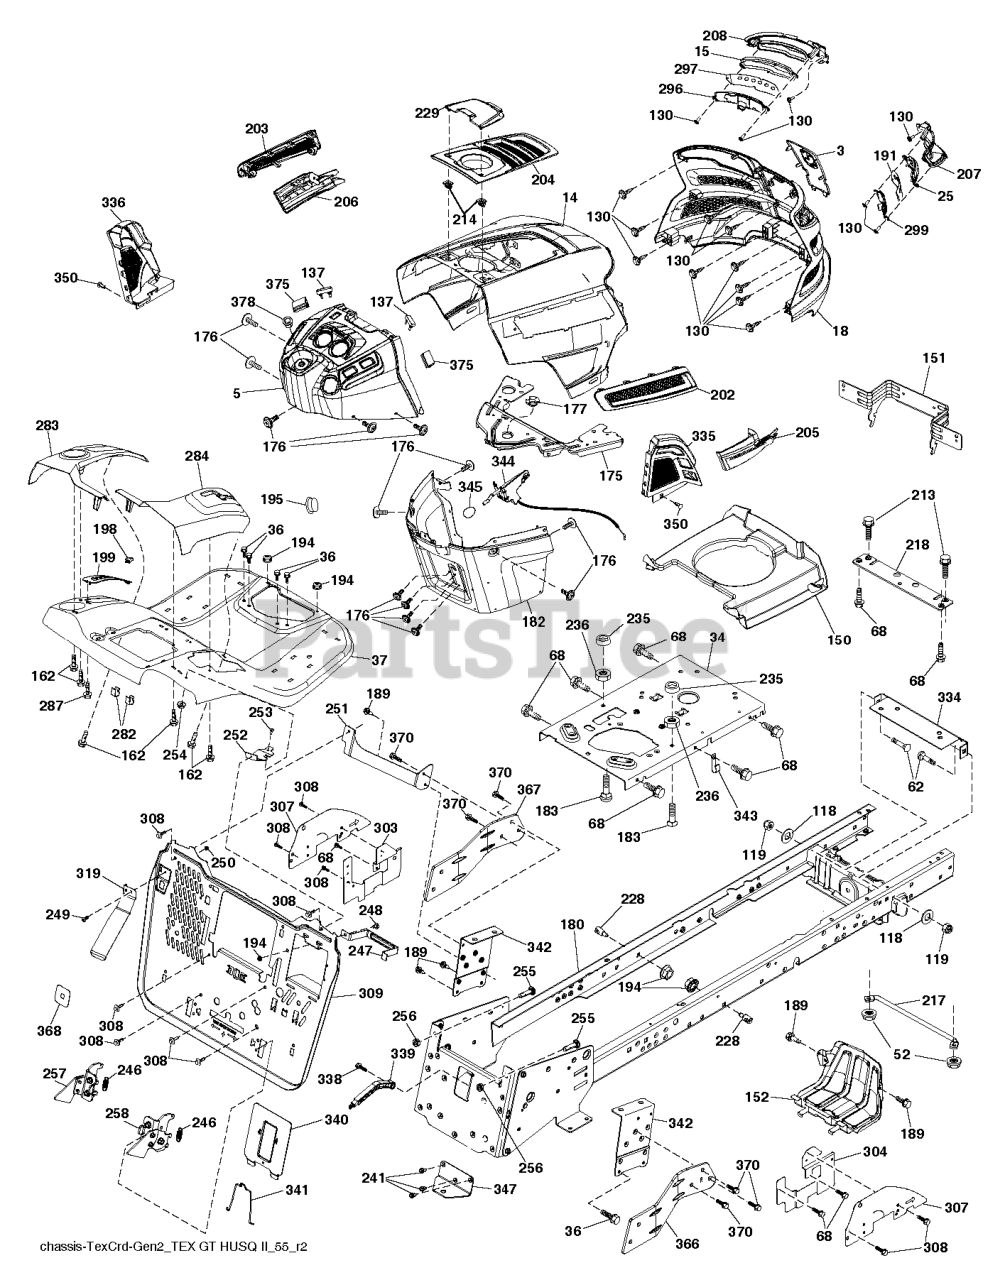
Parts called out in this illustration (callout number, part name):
3	APPLIQUE.SUBASM.GT.HUSQ.II
5	DASH.UPR.GT2.DUAL.RD.PTO.MC
14	HOOD.ASM.HUSQVARNA.GT.TEX.ORAN
15	LED LIGHT.LH
18	GRILLE SUBASM.GT.II.LOW.HDLGHT
25	LENS.RH
36	SCREW 5/16"
37	FENDER.TEX.SRD.CRD.FRN.GUARDS
118	WASHER PLAIN WASHER 3/8 X 0.08
137	BUMPER DASH
150	AIR.DUCT.GTV.BLACK
151	BRACKET.PIVOT.HOOD.GT.HUSQ.II
152	SHIELD.BROWNING.PNT.GT.V2
175	PLATE.PNT.CROSSMEMBER.HUSQ/PRE
176	SCREW.#10-24X5/8.RN.QU
177	BUSHING STEERING
180	CHASSIS WELDMENT.CRD2.BKP_BLTS
182	DASH.LOWER.COMMON.12V.ADAPTOR
189	SCREW
191	INSERT INFLECT.RH
195	PLUG.HOLE.DASH.LOWER.12V.BLK
198	INDICATOR.DECK.LIFT.RED
199	PLATE DECK LIFT
202	VENT.SIDE.RH.GT.HUSQ.II.
203	VENT.SIDE.LH.GT.HUSQ.II.498
204	VENT.TOP.ASM.HUSQ.GT2
205	SIDE.TRIM.RH.GT.HUSQ.II
206	SIDE.TRIM.LH.GT.HUSQ.II.GRAY
207	BEZEL GT2 LED RH W/ LOWER.ATT
208	BEZEL GT2 LED LH W/ LOWER ATT
213	SCREW HEXAGON HEAD SCREW 5/16-
214	CLIP.RETAINER.TINNER.
217	ROD.PIVOT.HOOD
218	X-PIECE.HOOD.STOP.NON/
228	STUD.W/"D"ANTI-ROTATION
229	LID.EXT.FILL.GT.HUSQ2.BLACK
236	NUT.CENTERLOCK.5/16-
246	SPRING.TCRD.GEN2.5.BAGGER.EXT
247	STRAP.BATTERY.TCRD.GEN2.5X431
248	BOLT.CARR.5/16-18X1/2
249	SCREW.BUTTONHD.10-24X1/2.(2 2)
251	BRKT.TOPSPPRT.BCKPLT.LH.CRD2.5
252	BRACKET.PNT.RH.SUPP.BKPLT.EDIP
253	BOLT CUP HEAD SQUARE NECK BOLT
254	NUT T
257	LATCH.ASM.BGR.LH.GEN2.5.STMPD
258	LATCH.ASM.BGR.RH.GEN2.5.STMPD
282	CLIP.RETAINER.CONSOLE.LT.HUSQ
283	CONSOLE.DECKLIFT.CRDII.498
284	CONSOLE.PEDAL.HYDRO
287	SCREW 1/4X20
296	LED LIGHT.LH
297	INSERT REFECT LH
299	LED LIGHT.RH
303	SHIELD.LWR.LH.30DECK/CRD1&2
304	SHIELD.LWR.RH.30DECK/CRD2PEDAL
307	SHIELD.UPPER.CRD.SRD.ISO
308	BOLT.5/16-18UNCX3/4 W/SEMS.BLK
309	BACKPLATE.TEXCRD2.5.BAGGER.479
319	LEVER.PRSNC.BGR.TEX.CRD.GEN2.1
334	BRACKET.ENGINE
335	COVER.LOWER.DASH.RH.BLACK
336	COVER-LH.LOWER.DASH.GT2.BLACK
339	LEVER LEVER BAGGER
340	BATTERY.DOOR.TCRD.GEN2.5.MS479
341	LATCH.BATTERY.DOOR.TCRD
342	SUPPORT.PNT.FENDER.CRD.TEX
343	CLIP CLIP
344	CONTROL.EZ.MULCH.TEX/CRD
345	RP KNOB.OVAL.TAPERED.3/8-16BLK
347	HITCH HITCH TOW TEX CRD GEN 2
350	CLIP.X-MAS.TREE
367	Brackets
368	FULL.LEVER.BAGGER.TEX.CRD
370	SCREW 3/8-16X1
375	BUMPER CLIP-ON. DASH 1"
378	BUSHING FLANGE; PLASTIC
